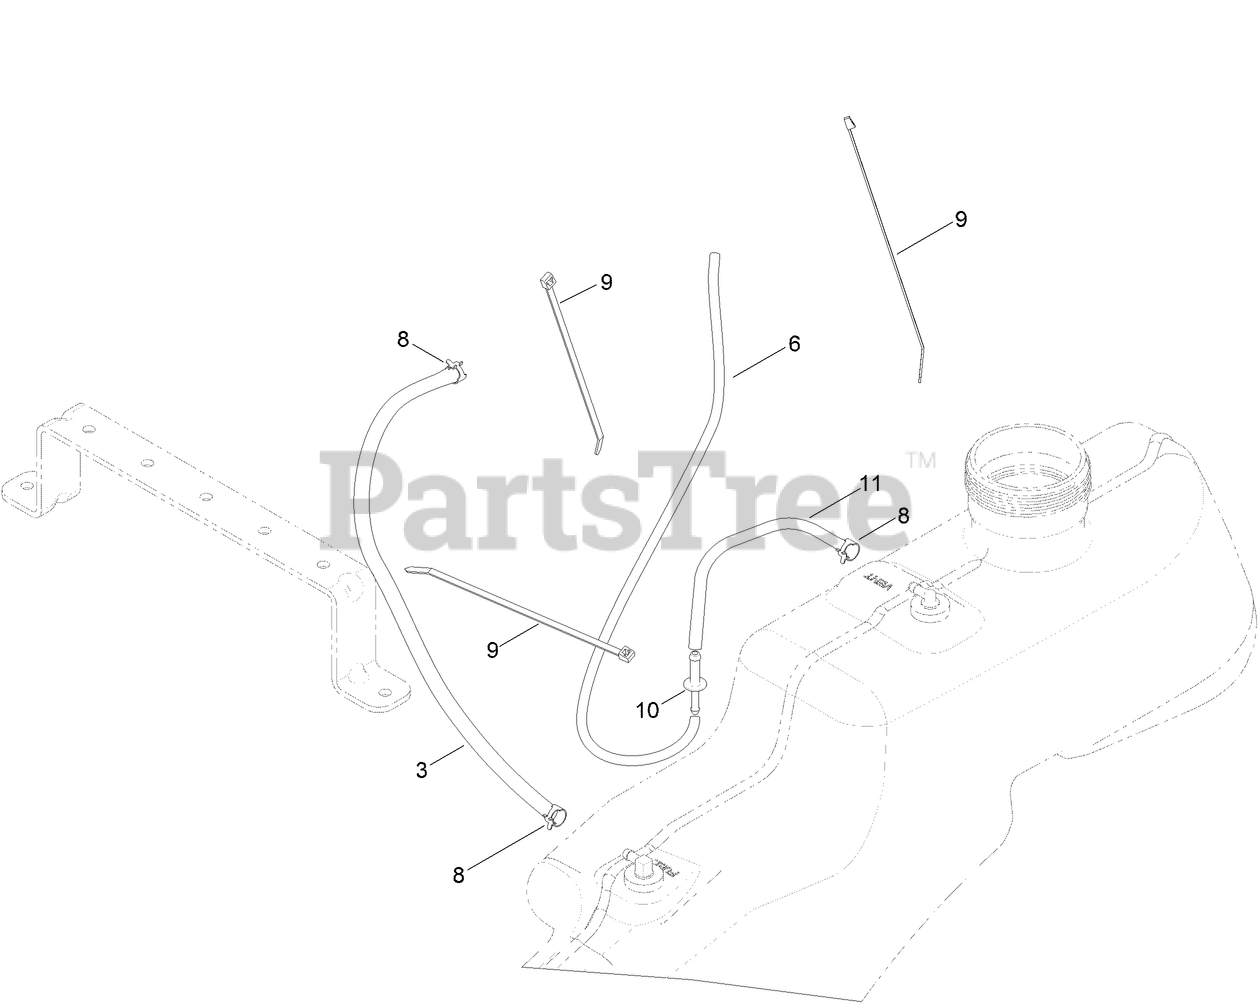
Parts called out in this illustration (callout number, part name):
3	HOSE-FUEL
6	HOSE-FUEL
8	CLAMP-HOSE
9	TIE-CABLE
10	ADAPTOR-ORIFICE
11	HOSE-FUEL
